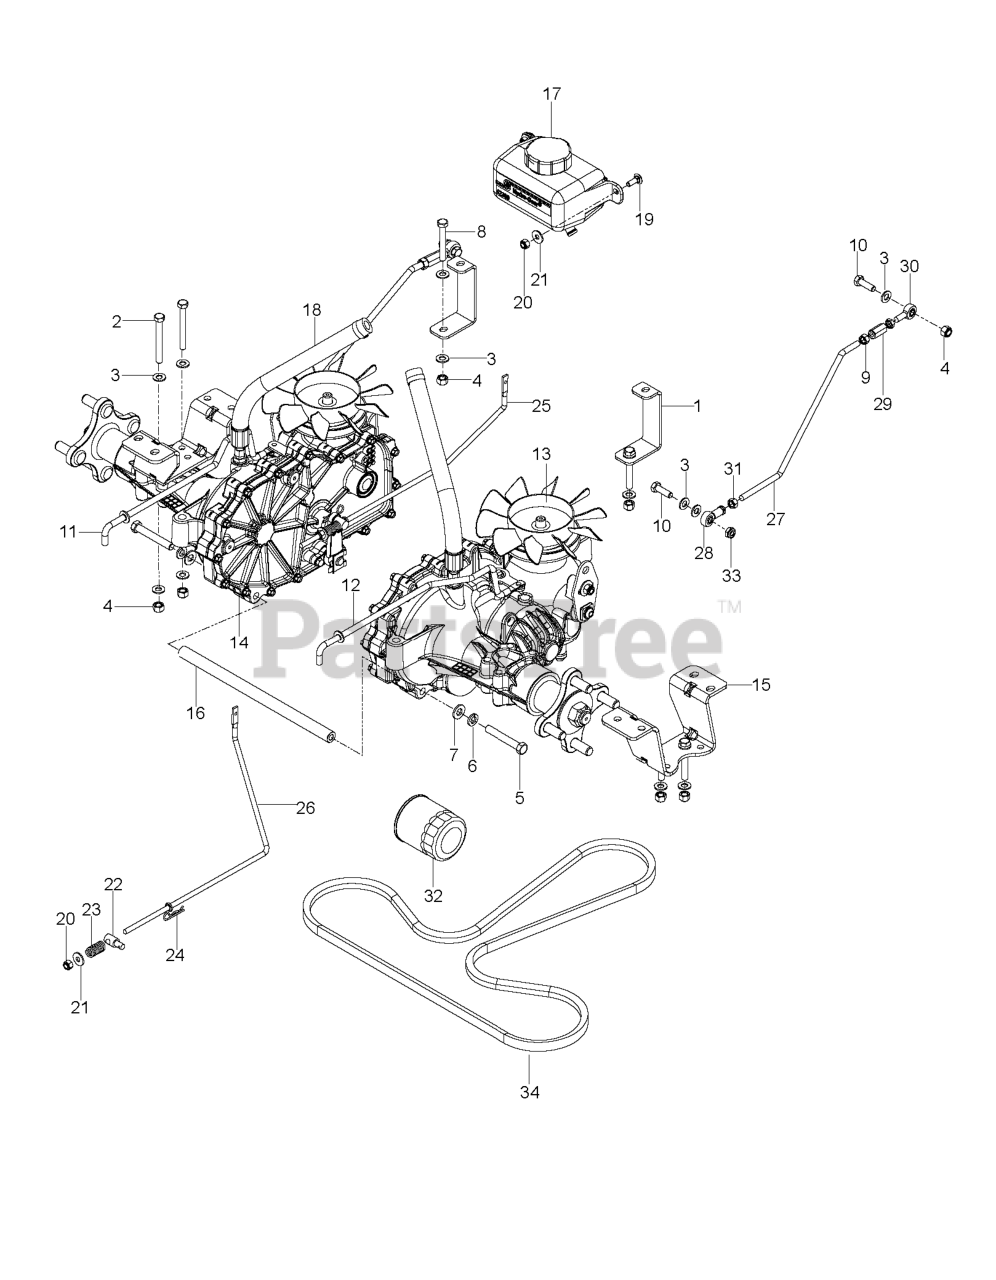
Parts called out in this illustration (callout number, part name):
1	SUPPORT.FRONT.TRANS.BLACK.
2	HCS 5/16C X 2-3/4
3	FLAT WASHER 5/16 SAE
4	NUT 5/16 NYLOC
5	HCS 3/8C X 2 1/2
6	SLW 3/8 STD
7	WASHER 3/8 SAE FLAT
9	NUT 5/16F LEFTHAND
10	HCS 5/16C X 1
11	ROD, BYPASS, RT
12	ROD, BYPASS, LT
13	HG_TRANS, ZT-2800 RT
14	HG_TRANS, ZT-2800 LEFT
15	EZT MOUNT, REAR, BLACK
16	SPACER TUBE, EZT, 11.08
17	HG_EXPANSION TANK W/CAP 71354
19	RHSNB 1/4C X 3/4
20	NUT.1/4-20.HEX.NYLOC.ZD
21	WASHER 1/4 FLAT
22	BRAKE SWIVEL
24	HAIRPIN #2
25	ROD EZT BRAKE LT
26	ROD EZT BRAKE RT
27	ROD, MOTION CONTROL
28	RH ROD END
29	ROD END COUPLER
30	RP.ROD.END.LH
32	HG_FILTER, ZT4800 52114
33	5/16-18 THIN PROF NY
34	BELT, EZT HYDRO
